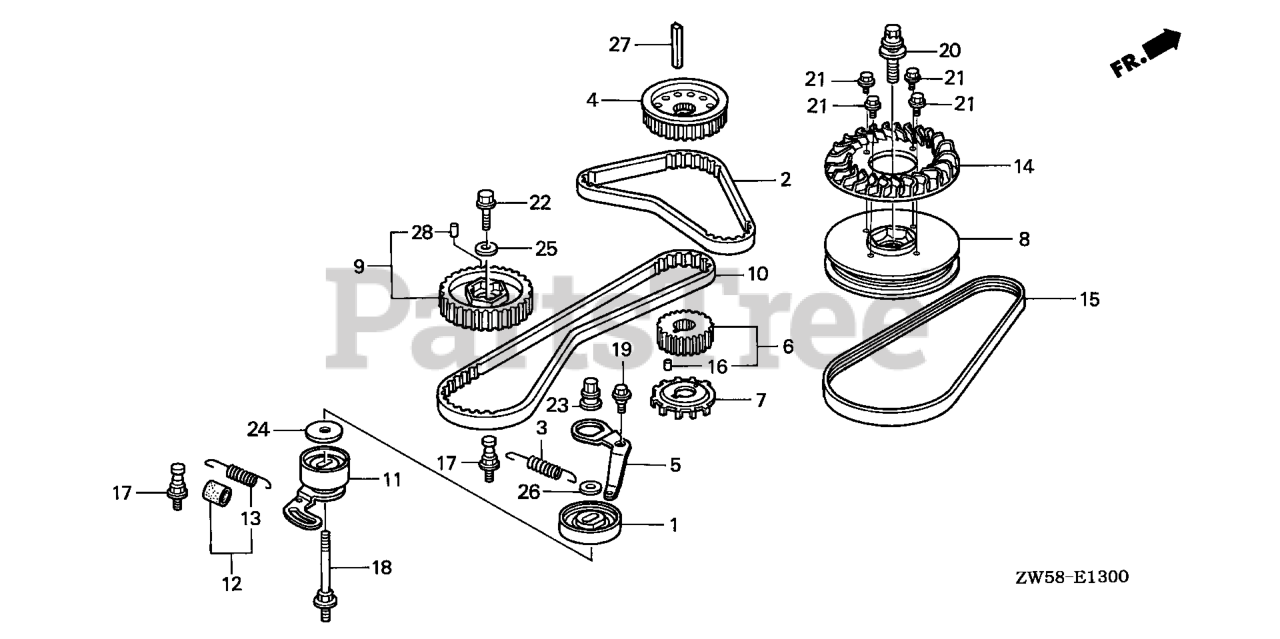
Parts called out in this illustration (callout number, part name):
1	TENSIONER, BALANCER BELT
2	BELT, BALANCER TIMING (UNITTA)
3	SPRING, BALANCER BELT ADJUSTER
4	PULLEY, BALANCER BELT DRIVE
5	BRACKET, B. BELT ADJUST
6	PULLEY, TIMING BELT DRIVE
7	PLATE, TIMING BELT GUIDE
8	PULLEY, CRANKSHAFT
9	PULLEY, TIMING BELT DRIVEN
10	BELT, TIMING (99RU24 B-333)
11	TENSIONER, TIMING BELT
12	SPRING, TIMING BELT ADJUSTER
13	SPRING, TIMING BELT ADJUSTER
14	FAN, COOLING
15	BELT, ALTERNATOR (4PK720 M150)
16	PIN, VERTICAL SHAFT
17	BOLT, TIMING BELT ADJUSTING SPRING
18	BOLT, TIMING BELT ADJUSTER
19	BOLT, BALANCER BELT ADJUSTER BRACKET
20	BOLT-WASHER (16X49)
21	BOLT, FLANGE (6X16)
22	BOLT, FLANGE (12X38)
23	NUT (10MM)
24	WASHER (10.5X44)
25	WASHER (12.5X34X5)
26	WASHER (10.3X25)
27	KEY (4.5X38.5)
28	ROLLER (4X10)
